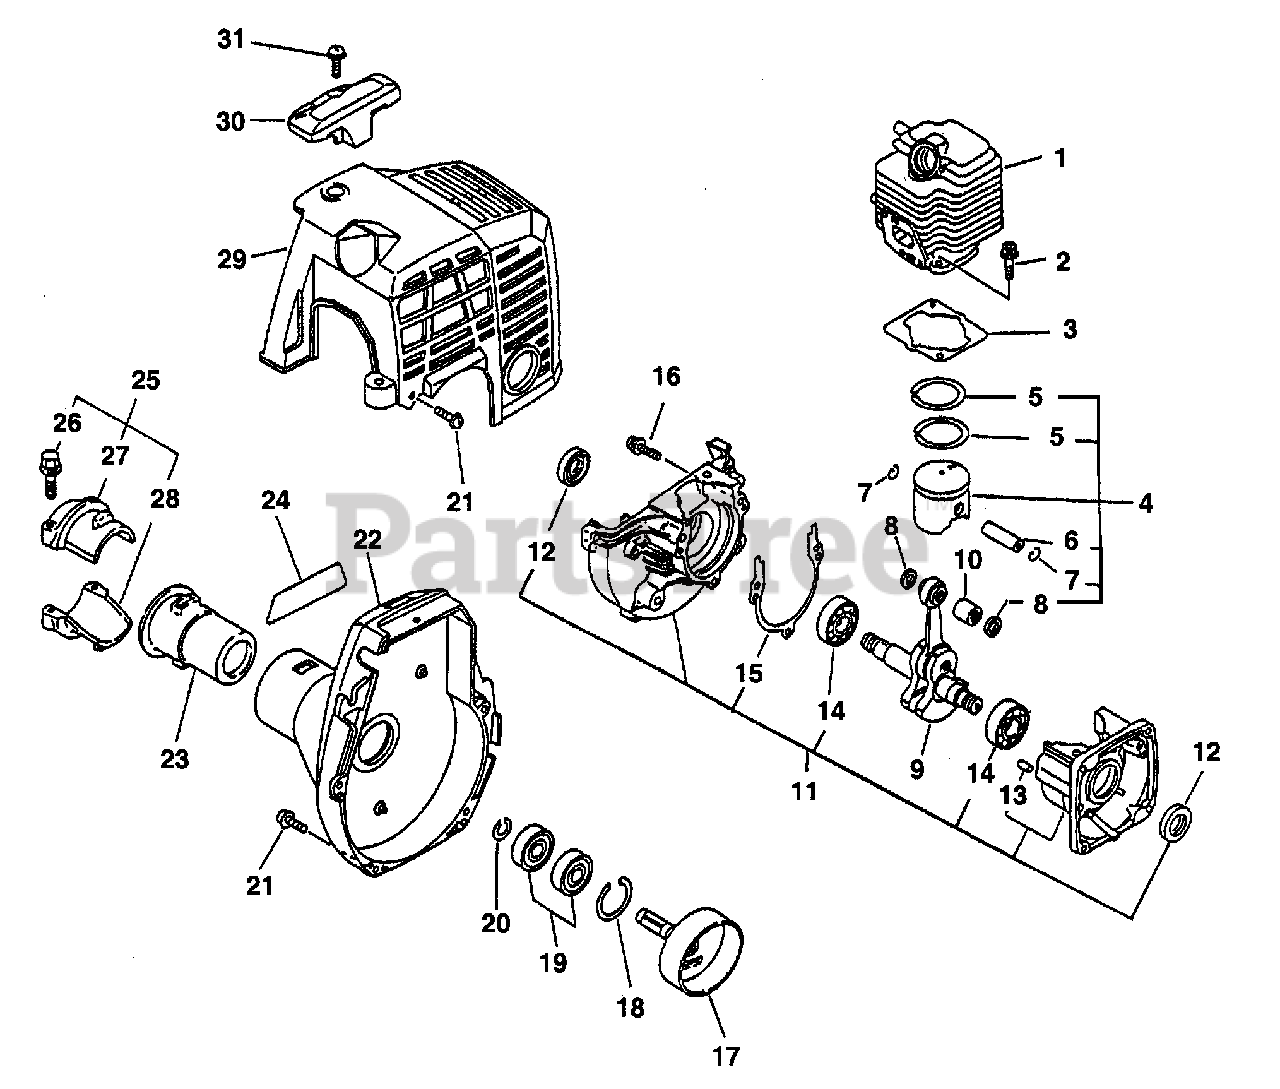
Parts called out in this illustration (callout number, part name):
1	Cylinder
2	Bolt, h.s. 5x22
3	Gasket, cylinder base
4	Piston kit
5	Ring, piston
6	Pin, piston
7	Circlip, piston pin
8	Spacer, piston pin
10	Bearing, needle
12	Oilseal
13	Pin, dowel
14	Bearing, ball 6201
15	Gasket, crankcase
16	Bolt 5x28
17	Drum, clutch
18	Circlip 28
19	Bearing, ball 6001
20	Circlip 12
21	Bolt 4x16
22	Cover asy, fan
24	Label, model
25	Holder kit
26	Bolt 5x25
29	Cover, cylinder
30	Guard, top
31	Screw 5x16
